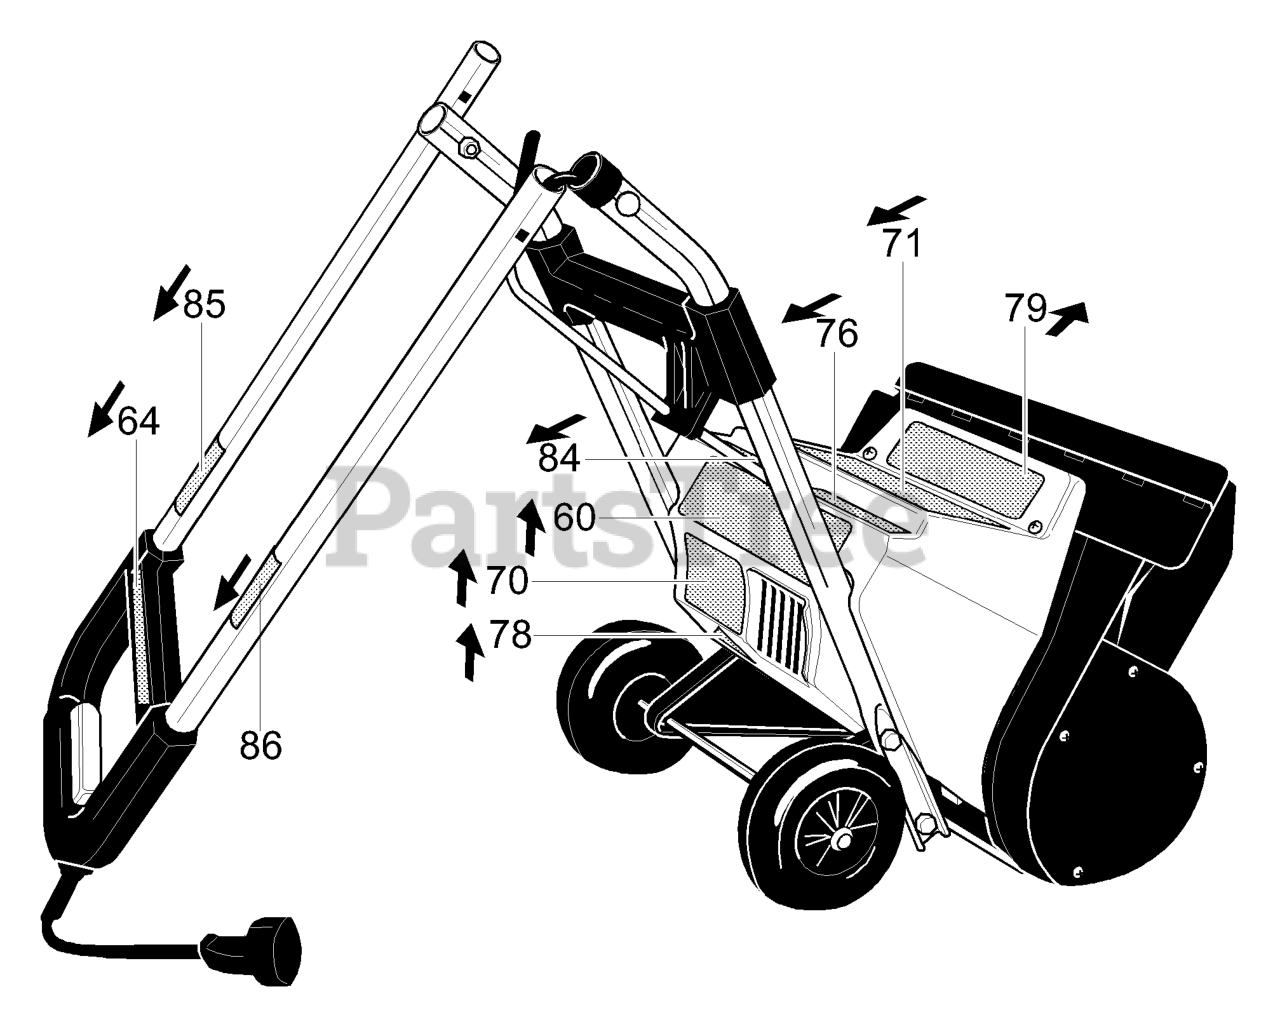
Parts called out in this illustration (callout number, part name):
60	Decal, Safe Operation
64	Decal, Start & Stop
70	NOT SERVICEABLE
71	Decal, MURRAY TURBO
76	Decal, Discharge Control
79	Decal, Danger Foot
84	Decal, Warning Cut-Out
85	Decal, Motor Protection, English
86	Decal, Motor Protection, French
